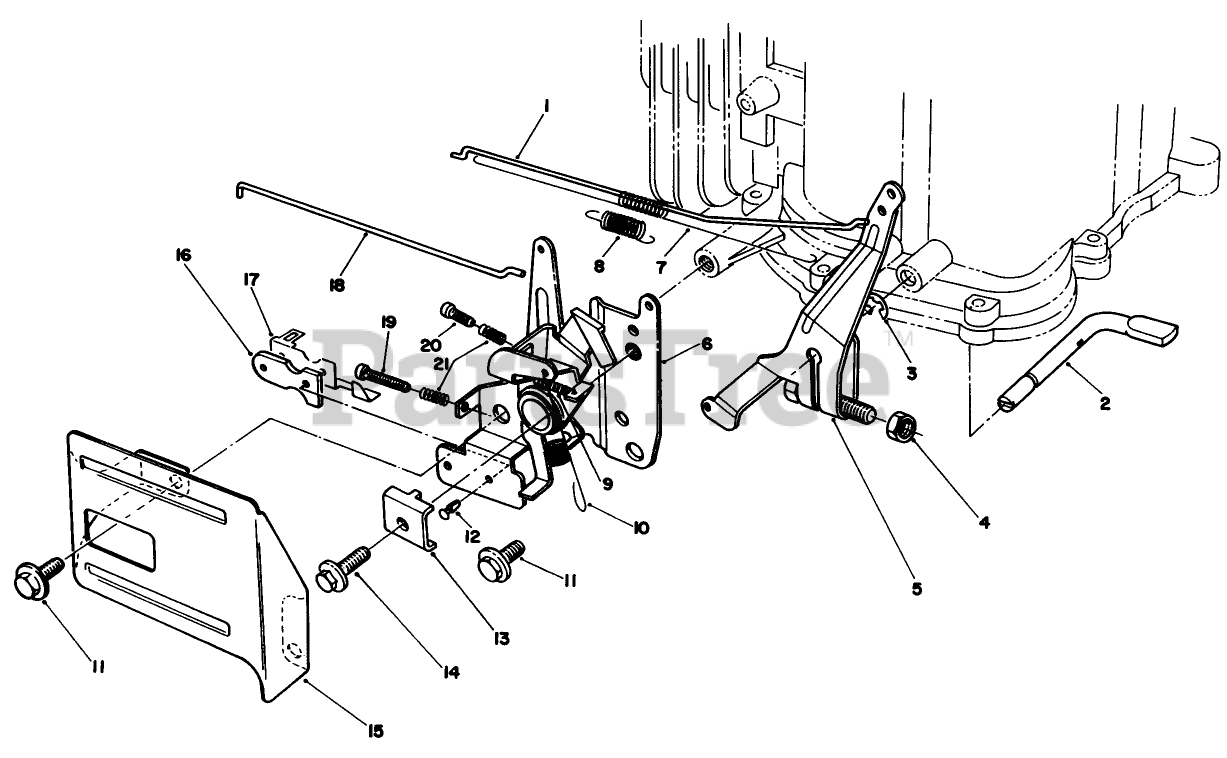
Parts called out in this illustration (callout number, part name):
7	SPRING
8	SPRING
10	SPRING
12	RIVET
13	CLAMP-CABLE
15	THROTTLE GUARD *
16	INSULATOR-KILL SWITCH
17	TERMINAL-KILL SWITCH
21	SPRING
